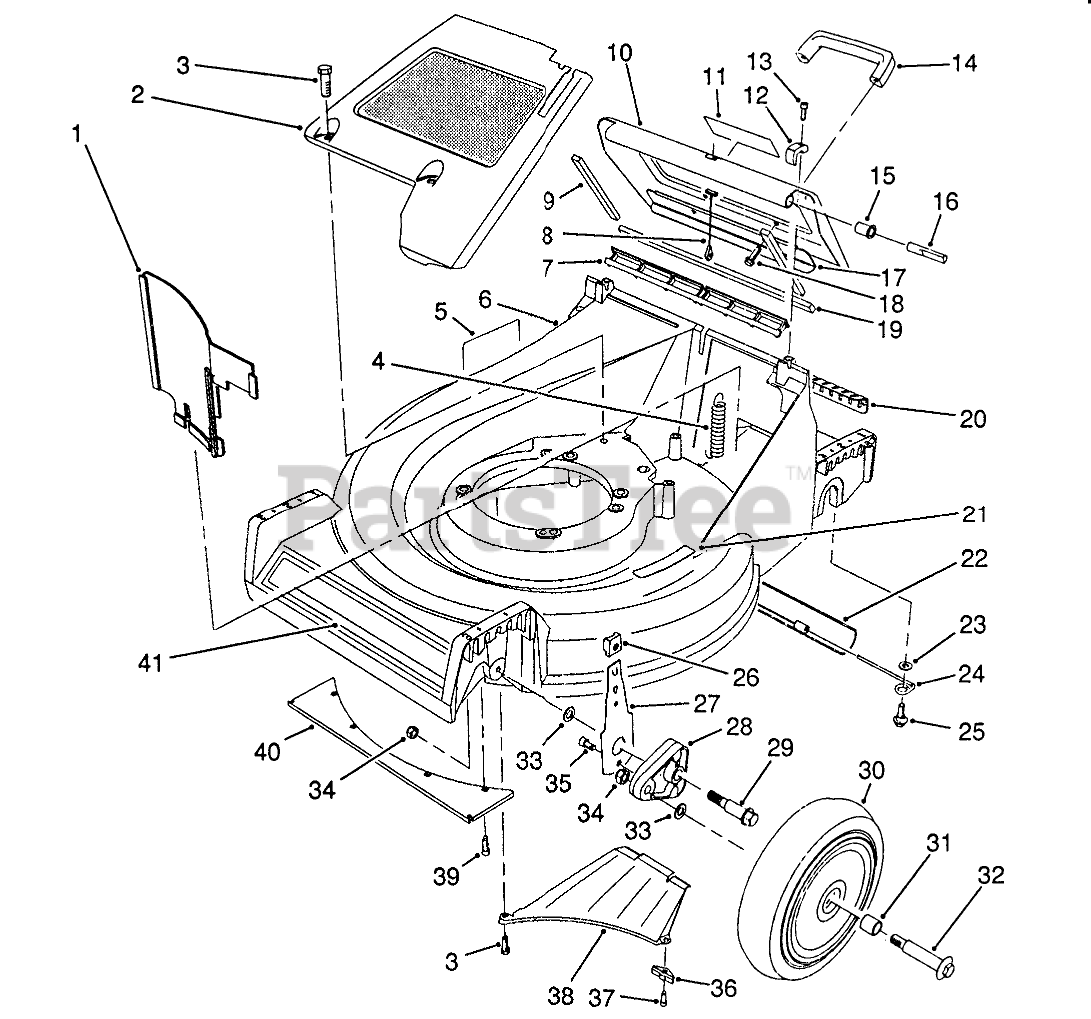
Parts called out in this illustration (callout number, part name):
1	PANEL-VERTICAL
2	PaneI-Screen
3	SCREW-HWHTF
4	EXTENSION-SPRING
5	Decal Danger
6	Housing-53cm (Incl. Ref. #5 & 21)(Model 26680 Only)
7	DOOR SEAL
8	DOOR CABLE
9	DOOR SIDE SEAL
10	Door-Discharge (Incl. Ref. #9, 11, 17 & 19)
11	DECAL - DANGER
12	HINGE CLAMP
13	SCREW-HSH
14	HANDLE-DOOR
15	DOOR BUSHING
16	HINGE PIN
17	DOOR - BRACE
18	SCREW-HWH
19	DOOR END SEAL
20	ACCESS COVER
21	DECAL - STEP PAD INT'L
22	TRAILING SHIELD
23	WASHER-PLAIN
24	SHIELD HANGER
25	SCREW-SHOULDER
26	KNOB-ARM
27	FRONT SPRING ARM ASM
28	ARM-PIVOT, FRONT
29	BOLT-SHOULDER
30	Wheel & Tire Assembly (Incl. Ref. #31)
31	BUSHING
32	WHEEL BOLT
33	WASHER
34	NUT-LOCK
35	SCREW-HSH, THREAD FORMING
36	Bracket-Discharge
37	SCREW-HWHTF
38	Ramp Discharge
39	SCREW-HWH
40	FRONT GUARD
41	DECAL - 53 CM
